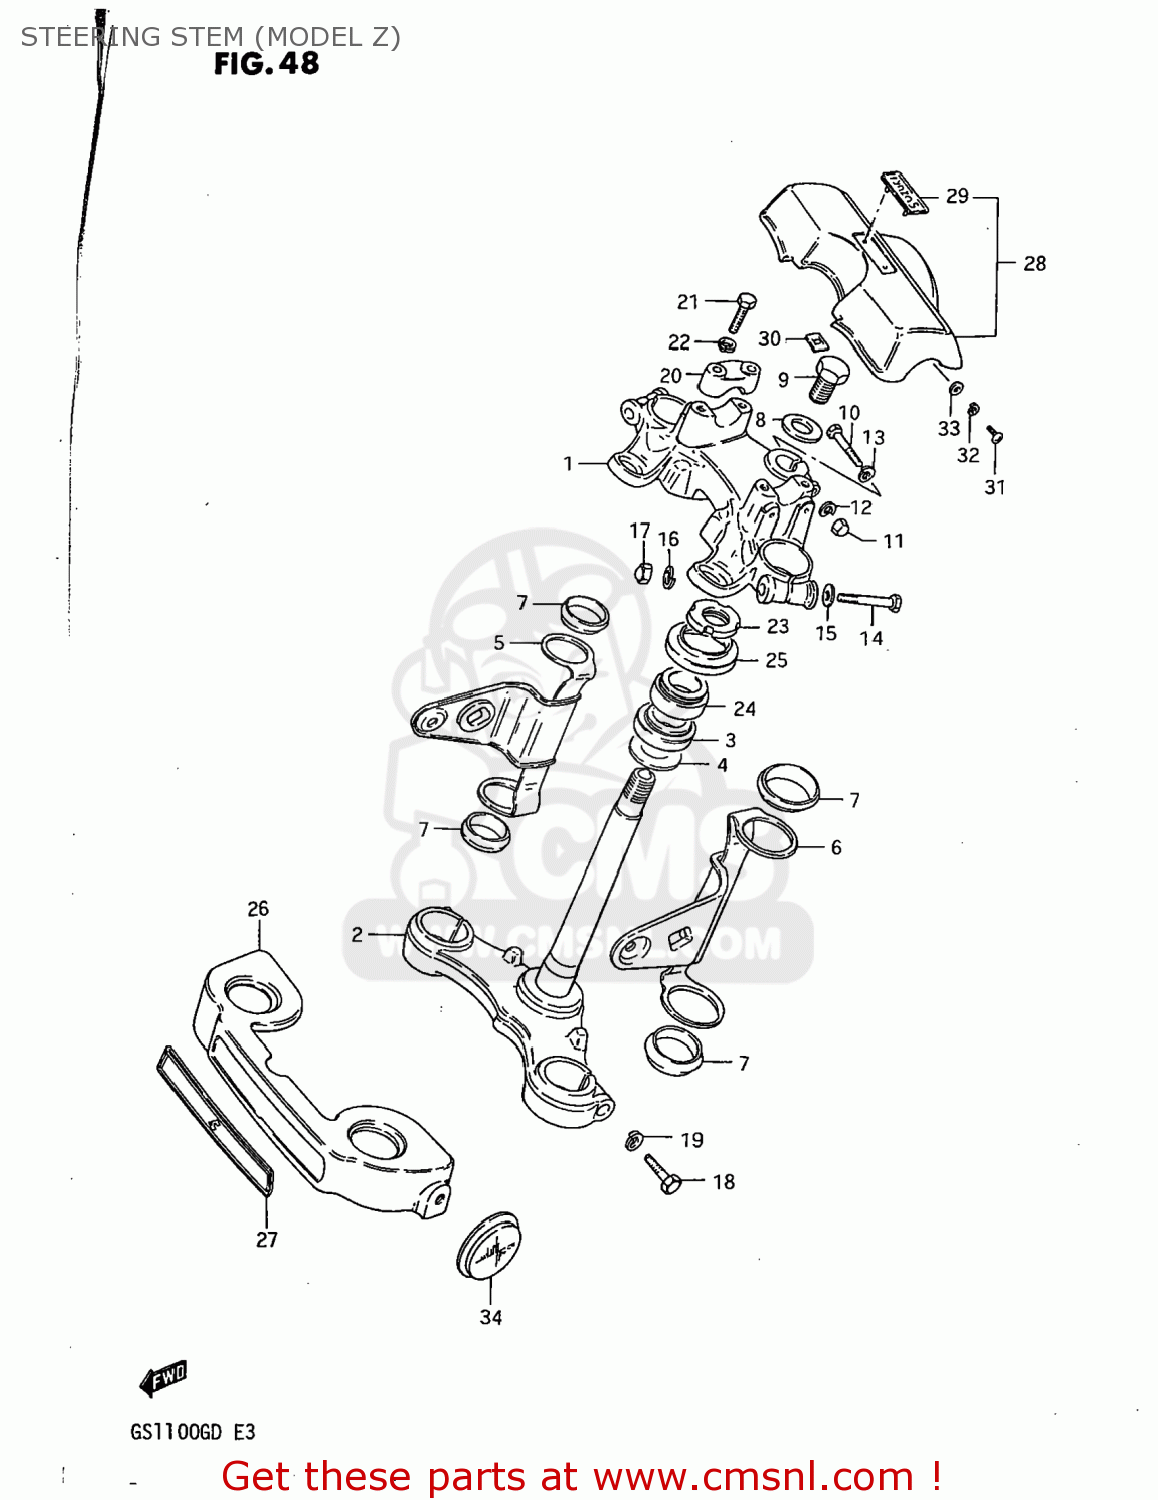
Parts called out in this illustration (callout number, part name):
1	HEAD,STEERING STEM
2	STEM,STEERING
3	BEARING
4	WASHER,THRUST
5	BRACKET,HEADLAMP,RIGHT
6	BRACKET,HEADLAMP,LEFT
7	CUSHION,HEADLAMP BRACKET
8	WASHER,STEERING STEM
9	NUT,STEM HEAD
10	BOLT 8X50
11	NUT
12	LOCK WASHER
13	WASHER
14	BOLT 10X55
15	WASHER
16	LOCK WASHER
17	NUT, LOWER LH
18	BOLT
19	LOCK WASHER
20	HOLDER,HANDLE(BLACK)
21	BOLT
22	LOCK WASHER
23	NUT,STEERING STEM
24	TAPER,ROLLER BEARING
25	DUST SEAL,STEERING UPR
26	COVER,FRONT FORK
27	EMBLEM,FRONT FORK COVER
28	PAD,HANDLEBAR
29	EMBLEM,HANDLE COVER PAD
30	NUT
31	SCREW
32	LOCK WASHER
33	WASHER
34	REFLEX REFLECTOR,RR
